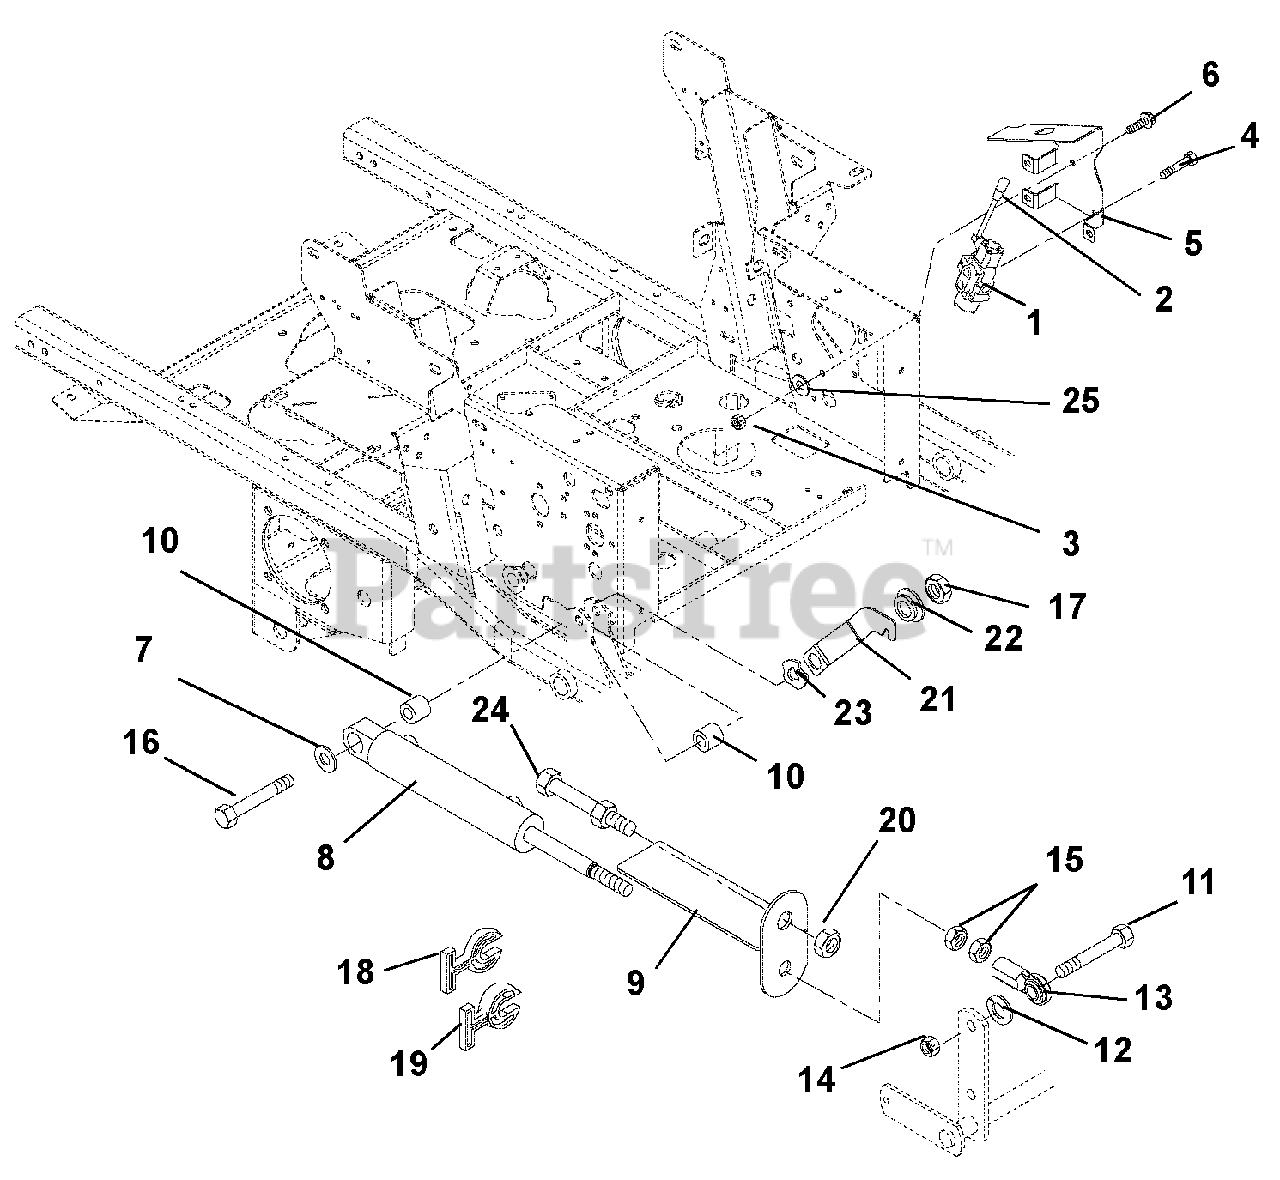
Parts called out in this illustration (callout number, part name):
1	Valve, Hydraulic Lift
2	Knob (Service Only)
3	Nut, Locking Center .31-18
4	Bolt, Hex .31-18 x 2.0 Grade 5
5	Bracket, Valve Mounting
6	Screw, Tapping Hex Washer Head .38-16 x .50
7	Washer, Flat Steel .515 x 1.625 x .25
8	Cylinder, Hydraulic Lift
9	Strap, Cut Indicator / Guard
10	Bushing .516 x 1.00 x 1.05
11	Bolt, Hex .62-11 x 2.25 Grade 8
12	Washer, Lock .62 x .156
13	Rod End, Right Hand Female .625
14	Nut, Locking Center .62-11
15	Nut, Jam .625-18
16	Bolt, Hex .50-13 x 3.75 Grade 5
17	Nut, Locking Top Flange .50-13
18	Stop, Cylinder .34 Thick
19	Stop, Cylinder .68 Thick
20	Nut, Jam .75-16
21	Latch, Footboard
22	Bushing, Flange .515 x .75 x .275 x 1.12
23	Washer, Wave .076 x 1.12 x .08
25	Washer, Locking .31 x .078 Regular
